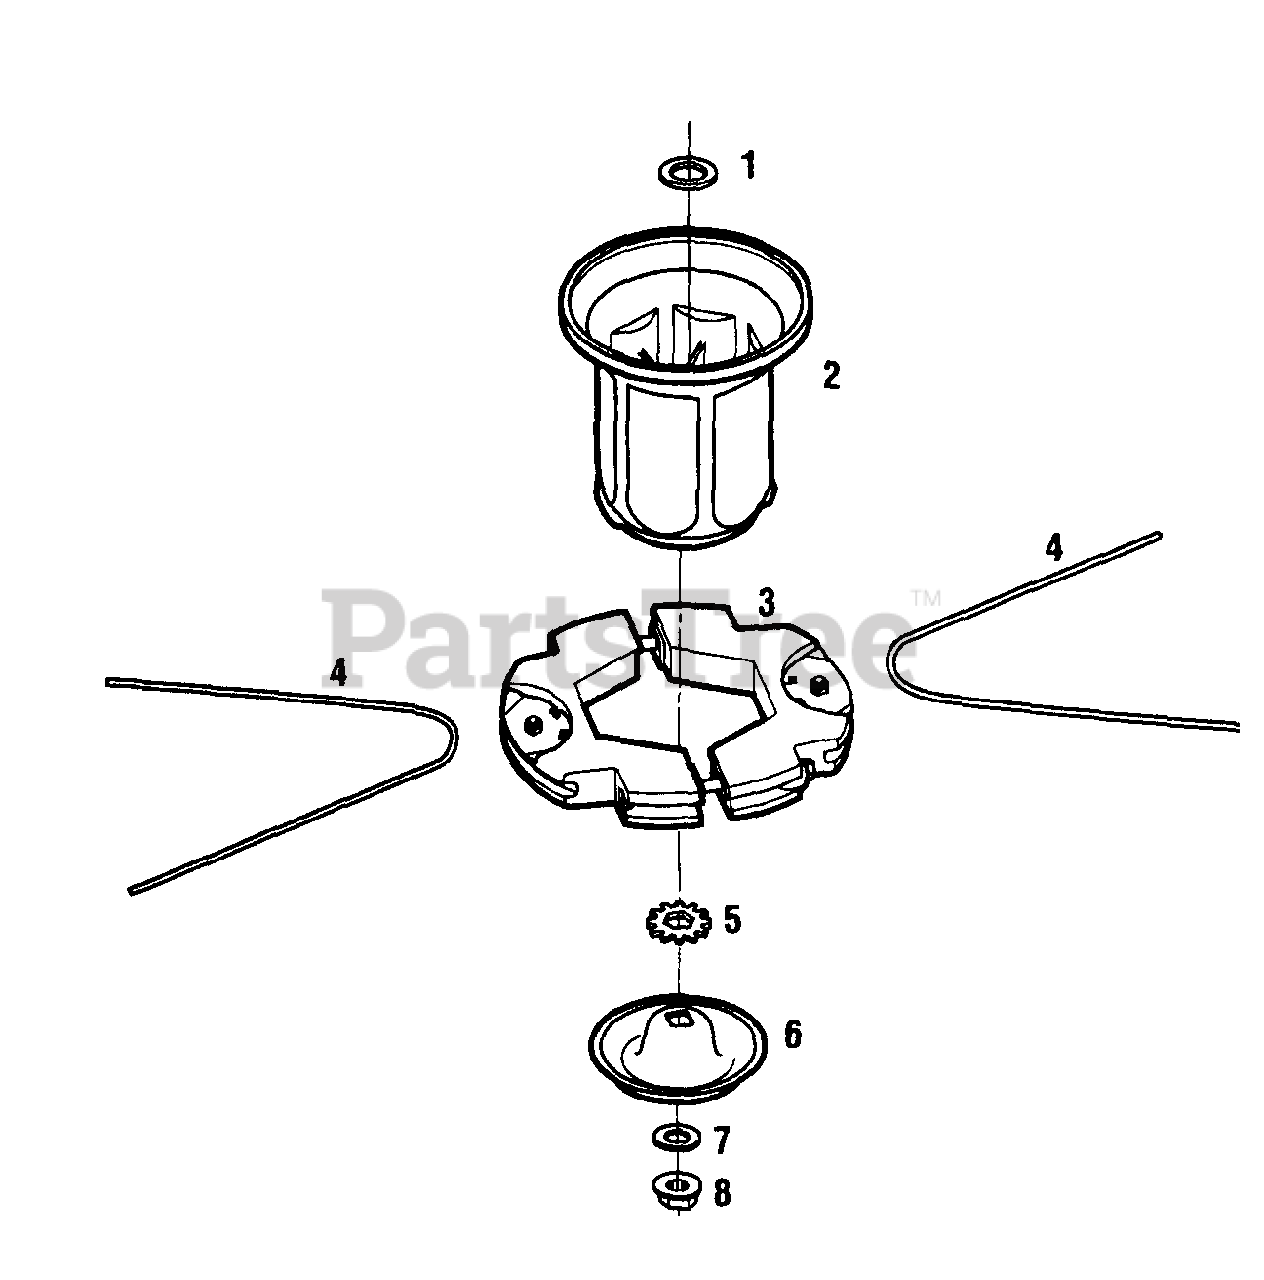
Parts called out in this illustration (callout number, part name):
1	Shoulder Washer
2	Spindle Head
3	Trimmer Head
4	Trimmer String
5	Hex Spline Washer
8	Hex Flange Nut, 1/2-13
